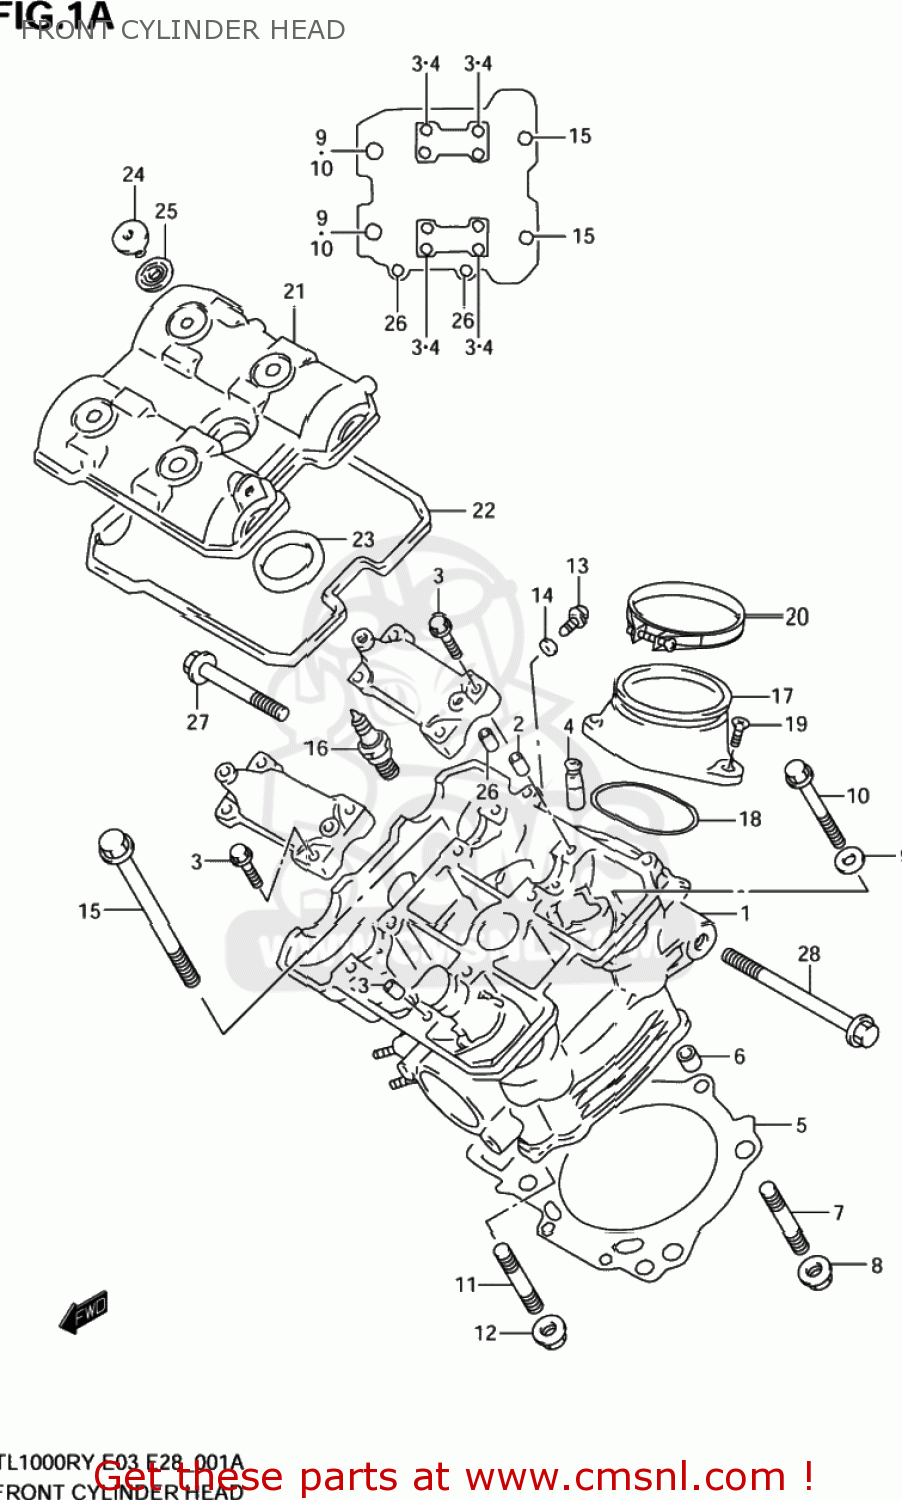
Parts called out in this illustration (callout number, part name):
1	HEAD ASSY,CYLINDER
2	PIN(6.2X8X11)
3	BOLT(6X39)
4	GUIDE,VALVE
5	GASKET,CYLINDER HEAD (NAS)
6	PIN
7	BOLT,STUD
8	NUT
9	WASHER(10.5X19X2)
10	BOLT,CYLINDER HEAD(L:175)
11	BOLT,STUD
12	NUT
13	BOLT
14	GASKET(5.8X13X1.2) (NAS)
15	BOLT(6X70)
16	PLUG,SPARK(CR9EK)
17	PIPE ASSY,INTAKE
18	O RING(D:2.4,ID:55.6)
19	SCREW
20	CLAMP
21	COVER,CYLINDER HEAD FR
22	GASKET,CYL HEAD COVER NO.1 (NAS)
23	GASKET,CYL HEAD COVER NO.2
24	BOLT(7X17.5)
25	WASHER(10.6X25.5X2.3)
26	PIN(6.2X8X11)
27	BOLT
28	BOLT
